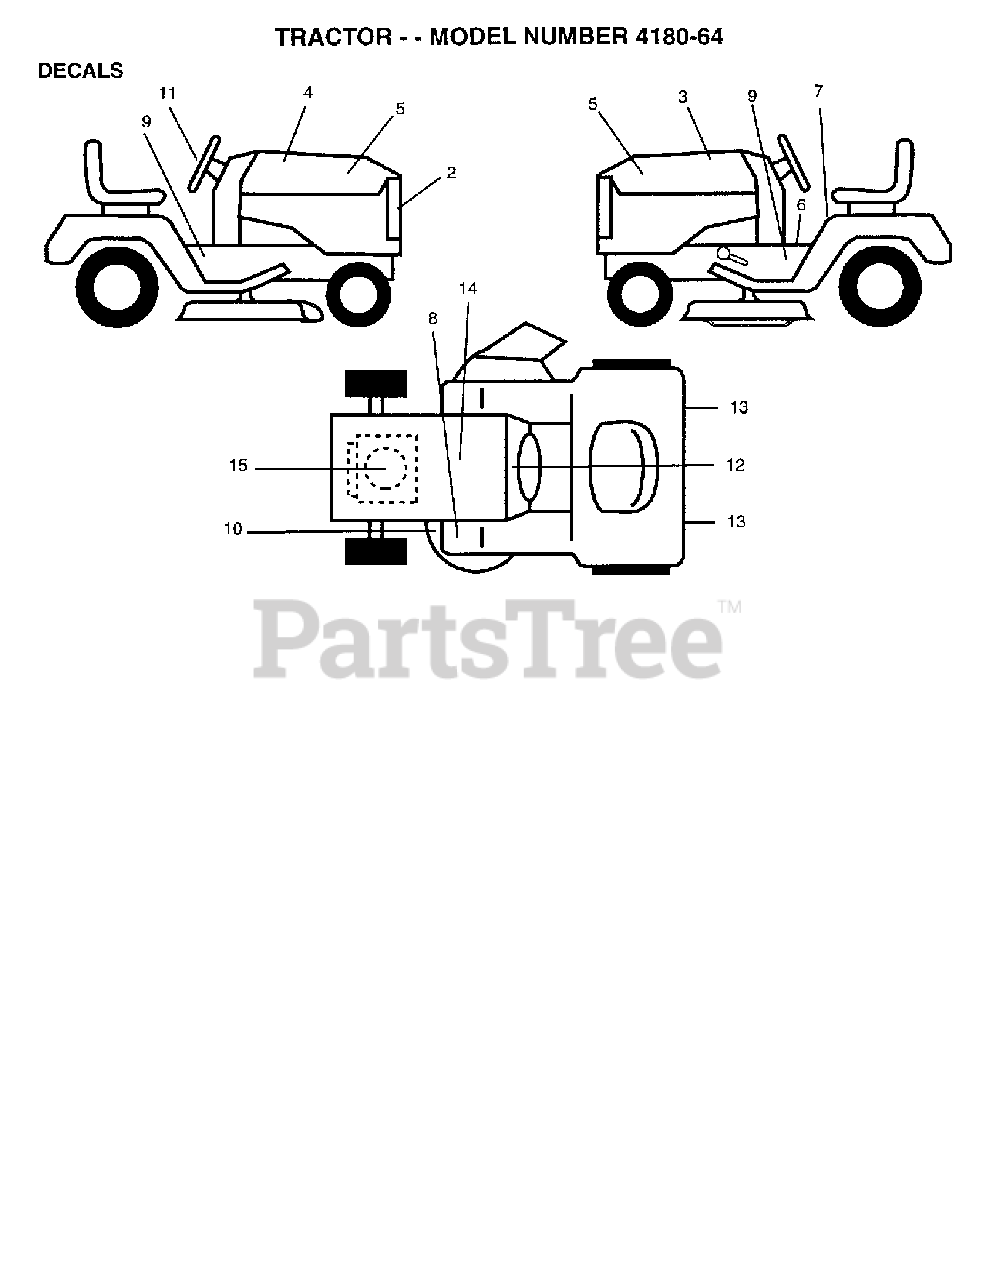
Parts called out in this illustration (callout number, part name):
2	Poulan TBD
3	Poulan TBD
4	Poulan TBD
5	Poulan TBD
6	DECAL PARK BRAKE
7	DECAL LT
9	Poulan TBD
11	Poulan TBD
13	REFLECTOR-TAIL YT
14	DECAL, BATTERY DANGER
15	Poulan TBD
